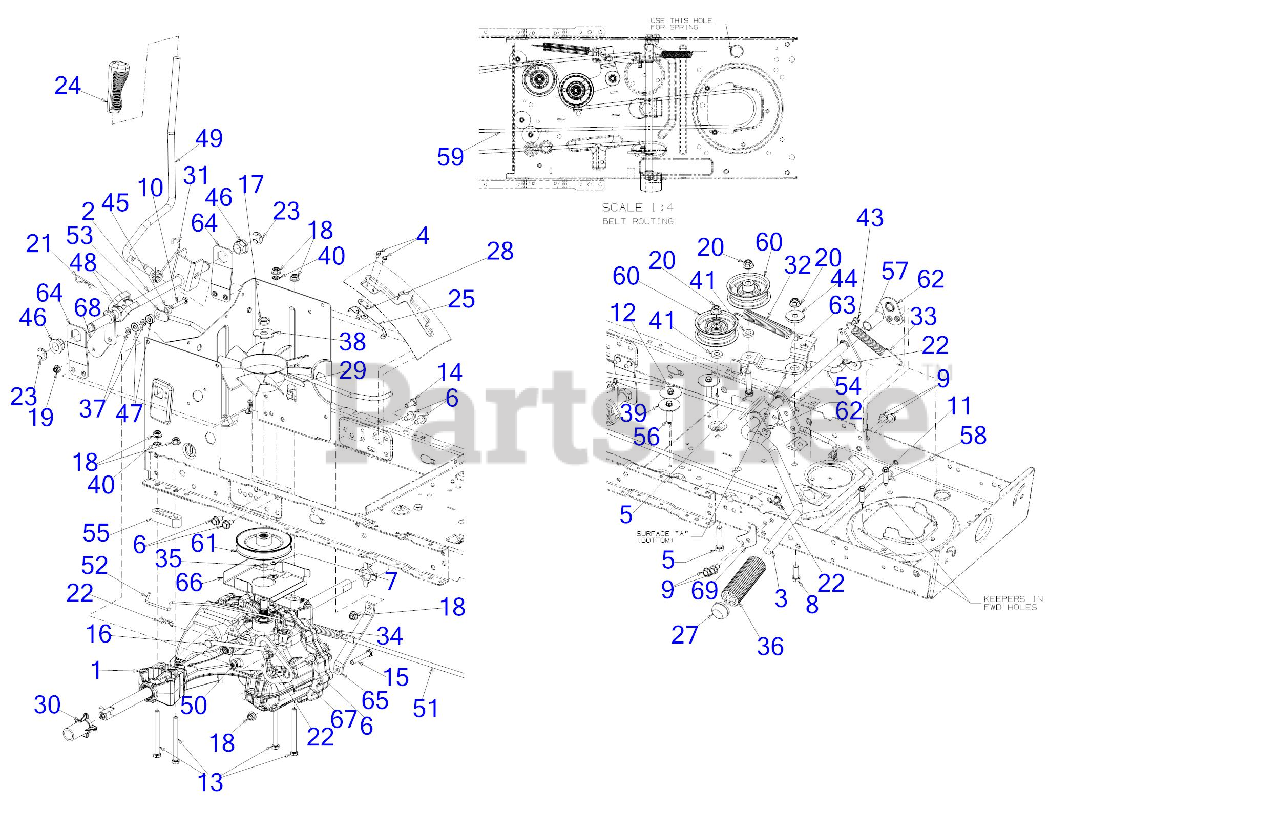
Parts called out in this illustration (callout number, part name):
1	HYDRO TRANSMISSION ASSEMBLY
2	CONTROL HANDLE ASSEMBLY
4	HEX SCREW WASHER HD #8-18 x 0.500
5	HEX SCREW 3/8-16 x 1.75 GR5
6	SCREW 5/16-18 x .750
7	SCREW-#10-24 x .400 SELF TAP
8	SCREW 3/8-16 x 1 GR5
9	SCREW 5/16-18 x .625
10	SCREW 1/4-20 x 1.50 GR.5
11	SCREW 1/4-20 x 1.25
12	SCREW 1/4-20 x 1.750
13	SCREW 5/16-18X3.5 GR5
14	SCREW 5/16-18 x .75 GR5
15	SCREW 5/16-18 x 2.0 GR5
16	FERRULE 5/16-24 x .312
17	NUT
18	FLANGE LOCK NUT 5/16-18
19	FLANGE LOCK NUT
21	INTERNAL COTTER PIN
22	BOW TIE COTTER PIN 1/4-5/16
23	E-RING
24	HANDLE GRIP
25	SPRING SWITCH
27	PUSH CAP
28	INSULATOR PLATE
29	HYDRO FAN
30	AXLE SLEEVE .765 ID x 2.11 LG
31	TORSION SPRING
32	EXTENSION SPRING .75 DIA x 6.02LG
33	EXTENSION SPRING .63 x 4.95
34	EXTENSION SPRING
35	WIRE RING
36	FOOT PAD
37	LOCK WASHER
38	LOCK WASHER
39	FLAT WASHER .350X1.59X.062
40	WASHER
41	FLAT WASHER
43	SHOULDER SCREW 1/4-20X.50 19"PSH
44	SHOULDER SPACER 1.375 x .380 X.154
45	SHOULDER SPACER
46	FLANGE BEARING
47	BALL BEARING .25 x .6875 x .25
48	SPLIT HEX FLANGE BEARING .628
49	CONTROL HANDLE
50	HYDRO CONTROL ROD
51	BRAKE ROD
52	HYDRO BYPASS ROD
53	HYDRO CONTROL ROD
54	HYDRO DECLUTCHING ROD
55	TRANSAXLE SPACER
56	SPACER:.260 x .372 x 1.420
57	SPACER
58	SPACER
59	V-BELT 4L x 84
60	FLAT IDLER PULLEY 2.75 OD
61	INPUT PULLEY
64	HYDRO HANDLE BRACKET
65	TORQUE BRACKET
66	BELT SUPPORT BRACKET
67	CAM BRACKET
68	PIVOT BRACKET
69	PEDAL STOP PLATE
